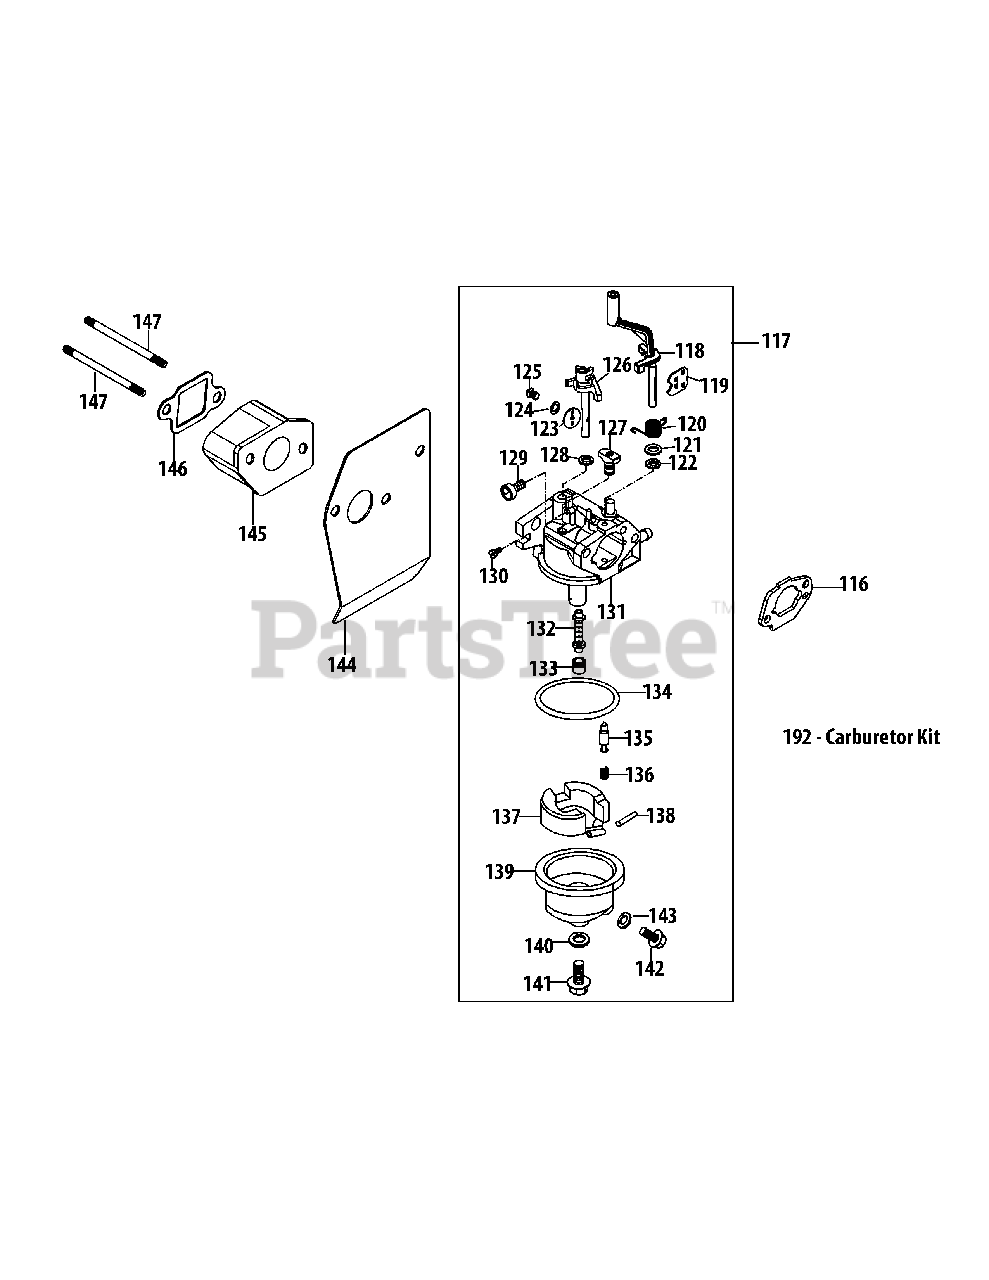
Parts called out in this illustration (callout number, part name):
116	Carburetor Gasket Plate
117	Carburetor Assembly
118	Choke Shaft
119	Choke Plate
120	Choke Return Spring
121	Choke Shaft Washer
122	Choke Shaft Fiber O-Ring
123	Throttle Plate
124	Throttle Plate Lock Washer
125	Screw M3X5 Throttle Plate
126	Throttle Shaft
127	Idle Jet Assembly
128	Throttle Shaft Fiber O-Ring
129	Idle Speed Adjusting Screw
130	Idle Mixture Screw
131	Carburetor Body
132	Emulsion Tube
133	Main Jet
134	Fuel Bowl O-Ring
135	Needle Valve
136	Needle Valve Spring
137	Float
138	Float Pin
139	Fuel Bowl
140	Fuel Bowl Gasket
141	Fuel Bowl Mounting Bolt
142	Fuel Drain Plug
143	Fuel Drain Plug Gasket
144	Carburetor Gasket
145	Carburetor Insulator
146	Carburetor Insulator Gasket
147	Carb Stud M6X113
192	Carburetor Kit - Major
